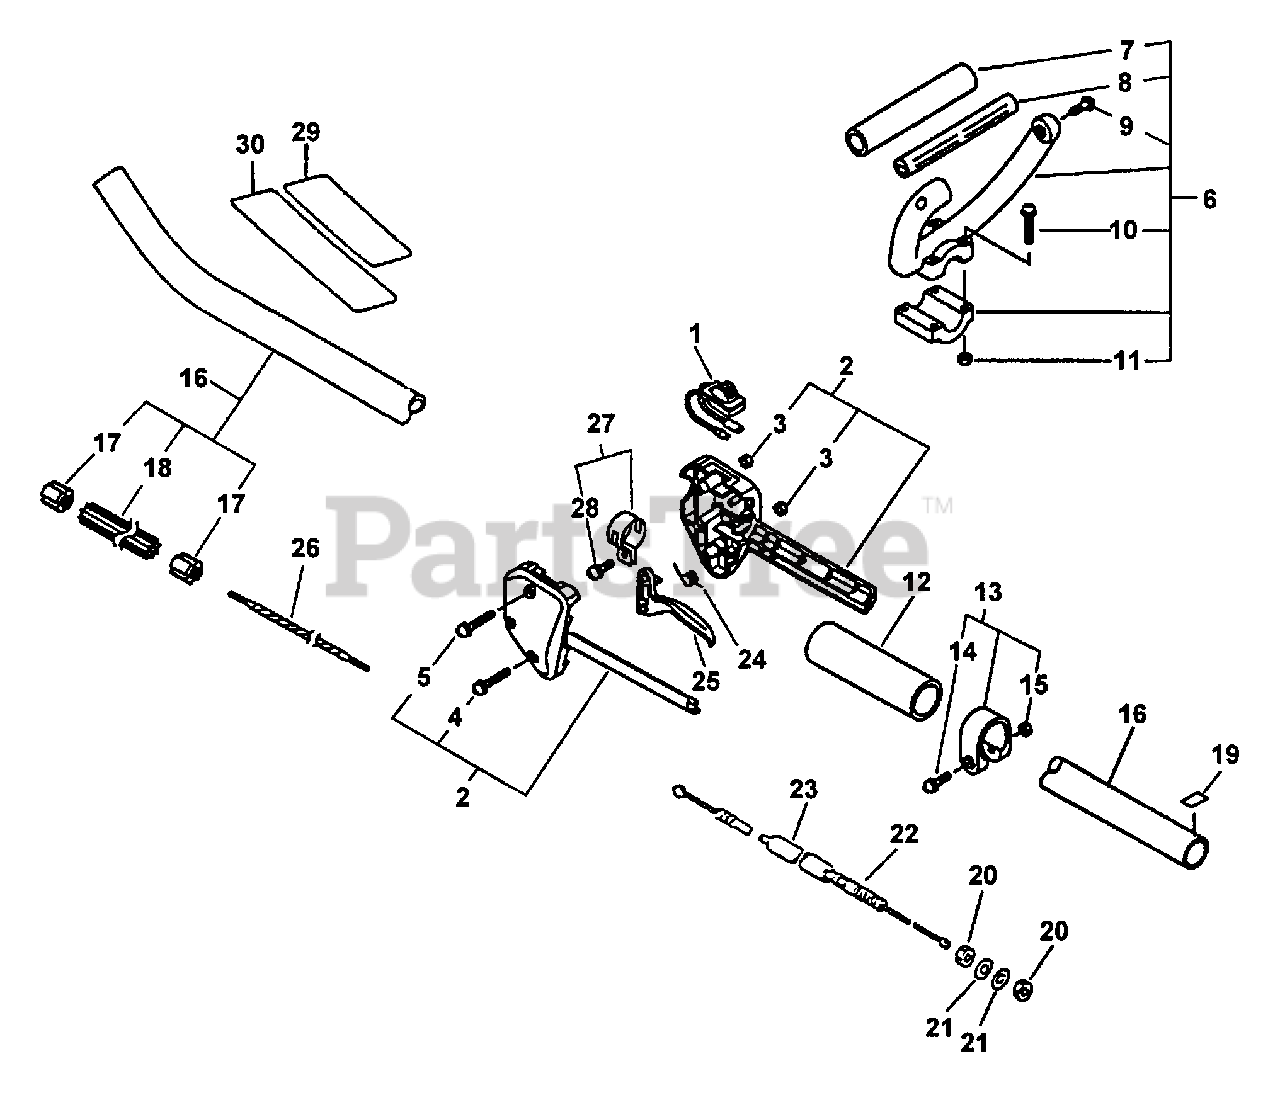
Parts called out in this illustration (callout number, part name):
1	IGNITION SWITCH ASSY
2	HANDLE KIT, CONTROL
3	NUT M5
4	SCREW 5×25
5	SCREW 5×35
6	LOOP HANDLE ASSY
7	GRIP, HANDLE
9	SCREW 5×30
10	SCREW 6×25
11	NUT, HEX M6
12	GRIP, HANDLE
13	CLAMP KIT
14	SCREW 5×28
15	NUT M5
16	MAIN PIPE ASSY
18	LINER, FLEXIBLE 21.6×1420
19	LABEL - ALIGNMENT
21	WASHER 6.5×11.5×0.8
22	CABLE, THROTTLE
23	TUBE
24	SPRING, TORSION
25	TRIGGER, THROTTLE
26	DRIVESHAFT - FLEXIBLE L= 1522
27	CLAMP KIT
28	SCREW 5×14
29	LABEL, CAUTION
30	LABEL, CAUTION
